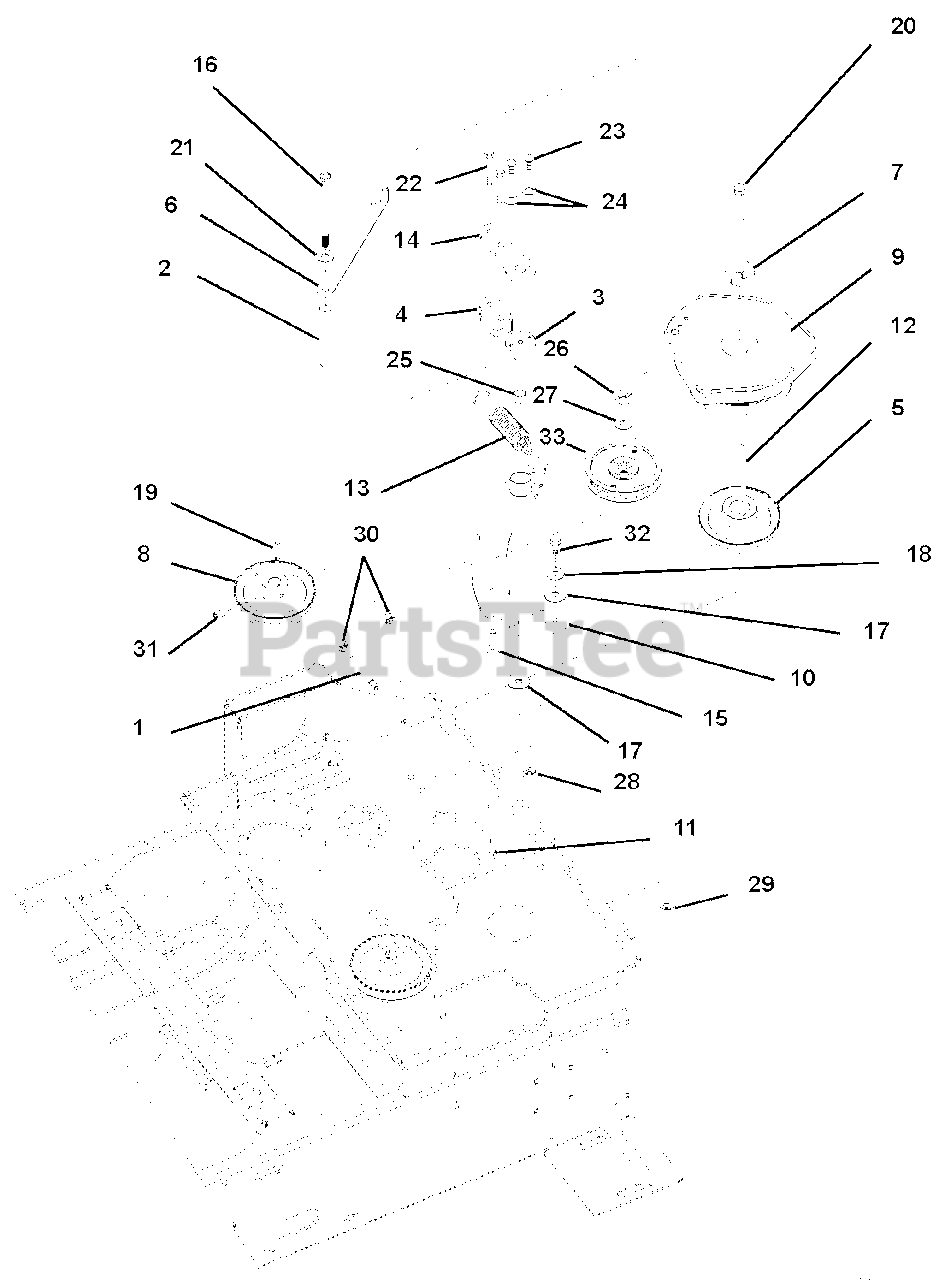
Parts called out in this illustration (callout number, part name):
1	Rod, Threaded Adjustment
2	Tube, RD .625 x .120 x 4.50
3	Pin, Tensioner Pivot
4	Plate, Spacer, Pump Tensioner
5	Pulley, V-Belt 5.00 x 1.13 w/key
6	Plate, Clutch Stop
7	Washer, Clutch Universal
8	Pulley, Pumps 4.78 PD 17MM
9	Clutch, ELECT - OGURA, GT3.5
10	Z Pump Belt Idler Arm Weldment
11	Belt, HA 64.2 EL (Hydraulic Pump)
12	Key, .25 x .25 x 4.62 SQr
13	Spring, EXT 1.188 x .162 x 4.25
14	Plate, Pump Tensioner Top
15	Bolt, .38-16 x 1.50 Flat Socket
16	Bolt, 3/8-16 x 5.50 HEX 5
17	Washer, .400 x 1.27 x .062 Nylon
18	Washer, .406 x 1.00 x .060 Flat
19	Key, M5 x M5 x M36 RE
20	Bolt, 7/16-20 x 2.25 HEX 5 EP80
21	Washer, Locking .38 x .094 Regular
22	Bolt, .38-16 x 2.00 Hex 5
23	Bolt, 1/4-20 x .500 Hex 5
24	Washer, Locking .25 x .062 Regular
25	Bearing, Sleeve .753 x .878 x .750
26	Nut, Spin Lock, Flange .375-16
27	Washer, .390 x .750 x .080 Flat
28	Nut, Locking, Flange .375-16
29	Nut, Spin Lock, Flange .312-18
30	Nut, .38-16 Standard Hex
31	Set Screw, 5/16-18 x .625 Square Cup
32	Bolt, .38 x .500 x 5/16-18
33	Pulley, Flat, 4.50 x .669 w/Brg
